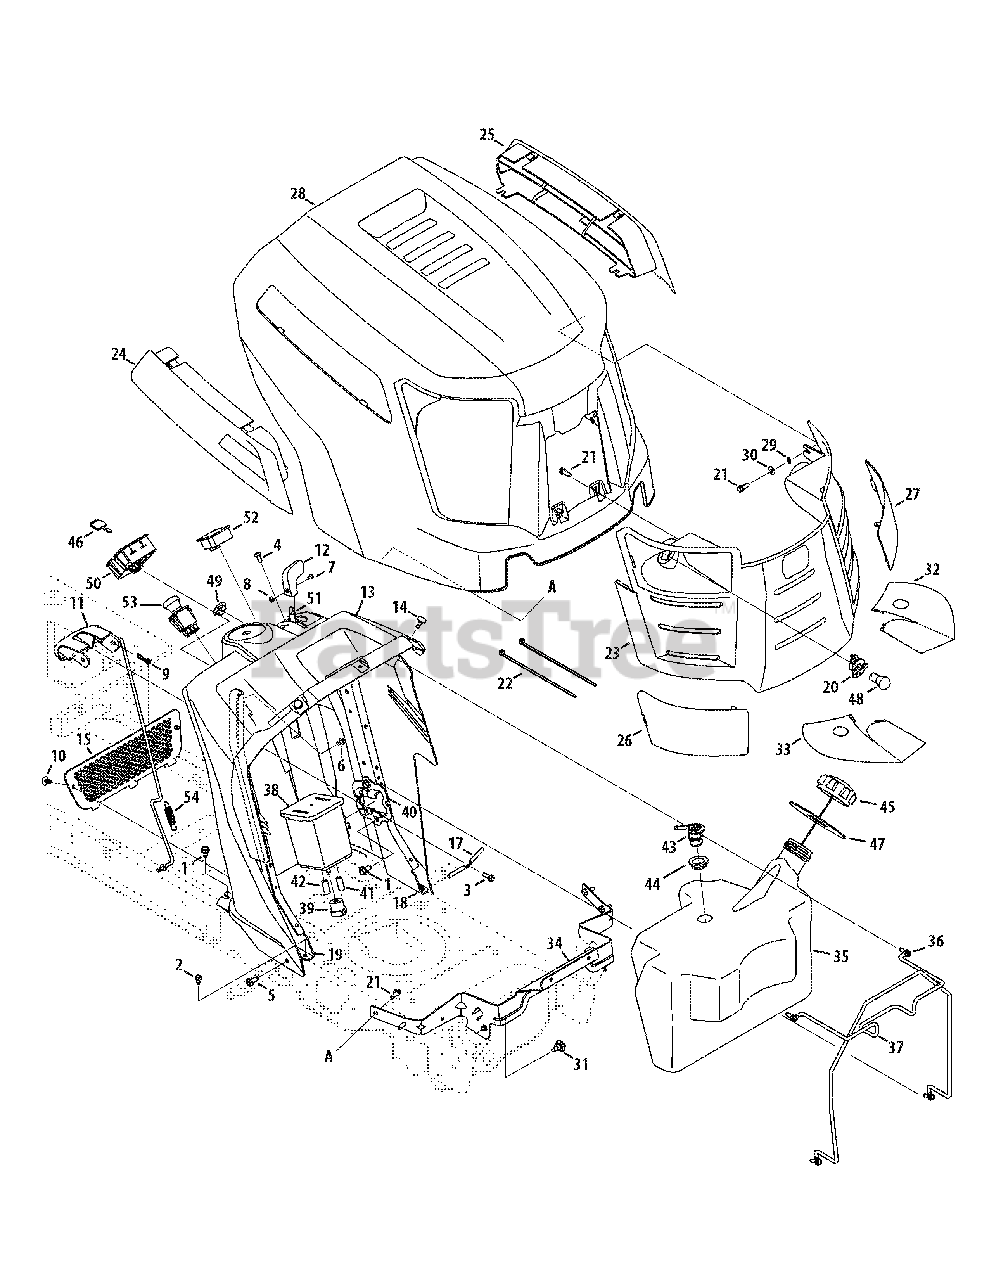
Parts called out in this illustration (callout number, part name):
1	Screw, Self-tapping, 5/16-18, .750
2	Screw, Self-tapping, 1/4-20, 0.500
3	Screw, HL, 1/4-15, 0.750
4	Screw, Ab, 1/4-14, 0.625,
5	Screw, Self-tapping, 5/16-18, 0.750,
6	Screw, Self-tapping, 1/4-20 x .625
7	Screw, Mach, #8-32, 0.375
8	Nut, Hex, #8-32
9	Pin, Cotter, Bow-Tie 72
10	Clip, Ratchet, .250 Dia
11	Lever, Dash, Cruise/Brake
12	Knob, Throttle
13	Dash Panel, A-Style
14	Bumper, .62 Dia X .3
16	Rod, Control, Latch Cub
17	Rod, Lever, Bent
18	Support, Dash, Plate LH
19	Support, Dash, Plate RH
20	Socket, Lamp
21	Screw, 1/4 Dia, .750
22	Tie, Cable, Push Mount 7.5 Lg
23	Grille Ass’y (Incl. 26, 27, 32 & 33)
24	Scoop, Hood, RH A-Style
25	Scoop, Hood, LH A-Style
26	Lens, Hood, RH A-Style
27	Lens, Hood, LH A-Style
28	Hood, A-Style
29	Washer, Lock, 1/4, External
30	Washer, Flat, .271, .630, .065
31	Screw, Shoulder, .43x.29, 5/16-18
32	Reflector, Cub A Style, LH
33	Reflector, Cub A Style, RH
34	Bracket, Pivot, Hood A-Style
35	Tank, Fuel, 3.75 Gal.
35	Tank, Fuel, 3.30 Gal. (CA)
36	Screw, Self-tapping, 1/4-20, .625
36	Screw, Self-tapping, 1/4-20, .75 (CA)
37	Rod, Support, Fuel Tank
38	Canister, Carbon, 5 Gallon (CA)
39	Filter, Vent, Canister (CA)
40	Bracket, Adapter, Canister (CA)
41	Hose, Fuel, Low Perm, 3/16 Wht (CA)
42	Hose, Fuel, Low Perm, 7/32 Yel (CA)
43	Valve, Rollover Grommet (CA)
44	Grommet, Rubber, 23.0 ID (CA)
45	Cap, Fuel
45	Cap, Fuel (CA)
46	Key, Ignition
47	Gasket, Fuel Tank
48	Lamp, 12v
49	Plug, Choke
50	Module Switch, Ignition
51	Cable, Throttle/Choke, 38"
52	Meter, Indicator
53	Switch, Electric PTO, Yellow
54	Spring, Extension, .500 Dia x 2.733
